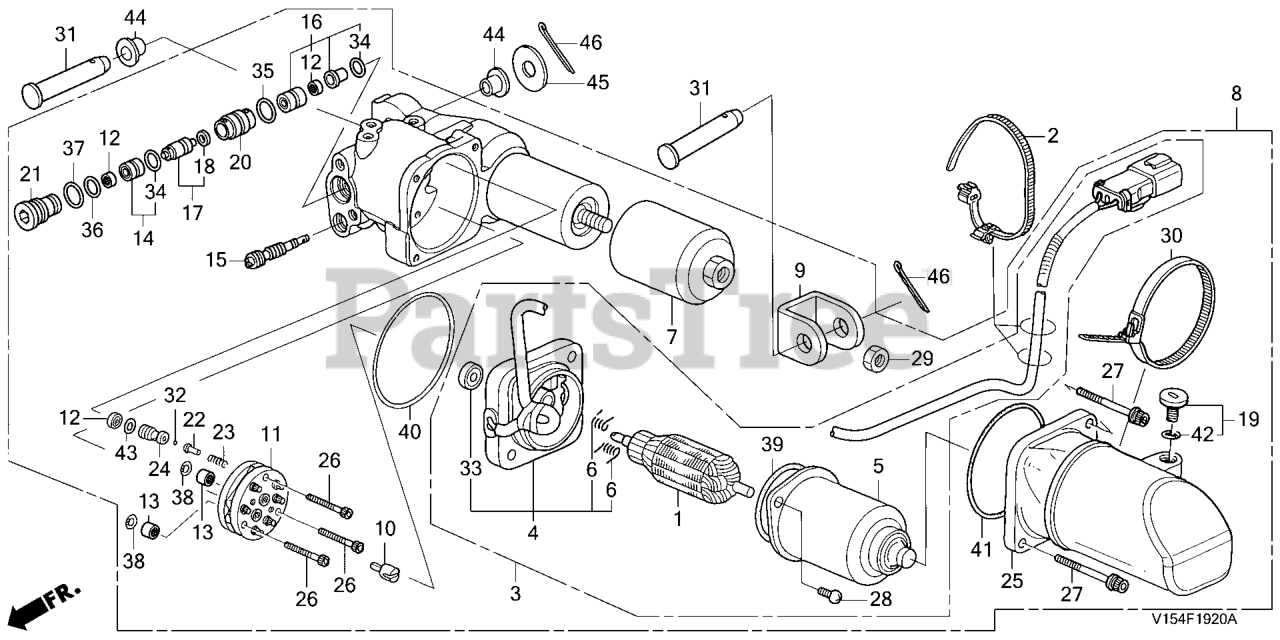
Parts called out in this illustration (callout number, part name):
2	BAND, WIRE HARNESS
3	MOTOR ASSY., POWER ROLLING
4	BRACKET ASSY.
6	SPRING, MOTOR
7	COVER, DUST END
8	ROLLING ASSY., POWER
9	JOINT, METAL
10	JOINT, DRIVE
15	VALVE, MANUAL
17	SPOOL, VALVE
18	RING, BACK-UP
19	BOLT, PLUG
22	GUIDE, SPRING
23	SPRING, VALVE
24	SEAT, VALVE
26	BOLT, SOCKET
27	BOLT, SOCKET
28	SCREW, PAN (5X0.8)
30	BAND, WIRE HARNESS
31	PIN (12X46)
32	BALL, STEEL
34	O-RING (1.5X10.7)
35	O-RING (1.5X13.5)
36	O-RING (1.5X15.5)
37	O-RING (1.8X18.8)
38	O-RING (1.5X8.5)
40	O-RING (2.0X62.5)
41	O-RING (2.4X66.6)
42	O-RING (1.9X9.8)
43	O-RING (1.5X5.5)
44	BUSH, CYLINDER (UPPER)
45	WASHER, PLAIN (12MM)
46	PIN, SPLIT (3.0X25)
46	PIN, COTTER (3.0X45)
